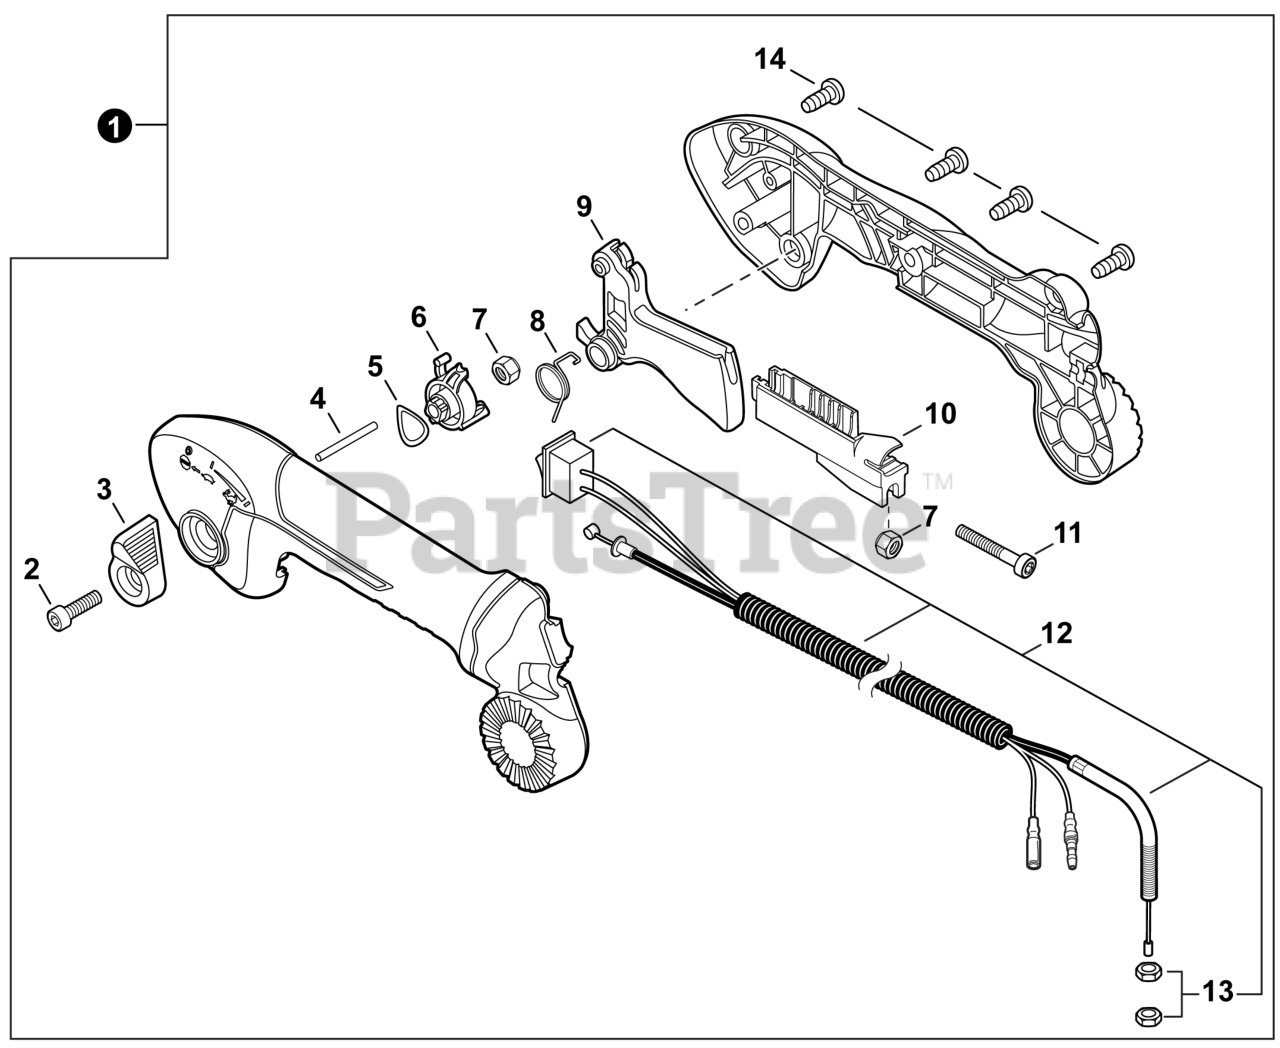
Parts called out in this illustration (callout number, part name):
1	THROTTLE CONTROL KIT - TUBE MOUNT
2	BOLT, TORX 5x20
3	LEVER, THROTTLE
4	PIN 3x32
5	WASHER, WAVE 12
6	CONTROL, THROTTLE
7	NUT, LOCK M5
8	SPRING, TORSION
9	TRIGGER, THROTTLE
10	CONNECTOR, CABLE
11	BOLT, TORX 5x30
12	CABLE ASSY, CONTROL
14	BOLT, TORX 5x16
